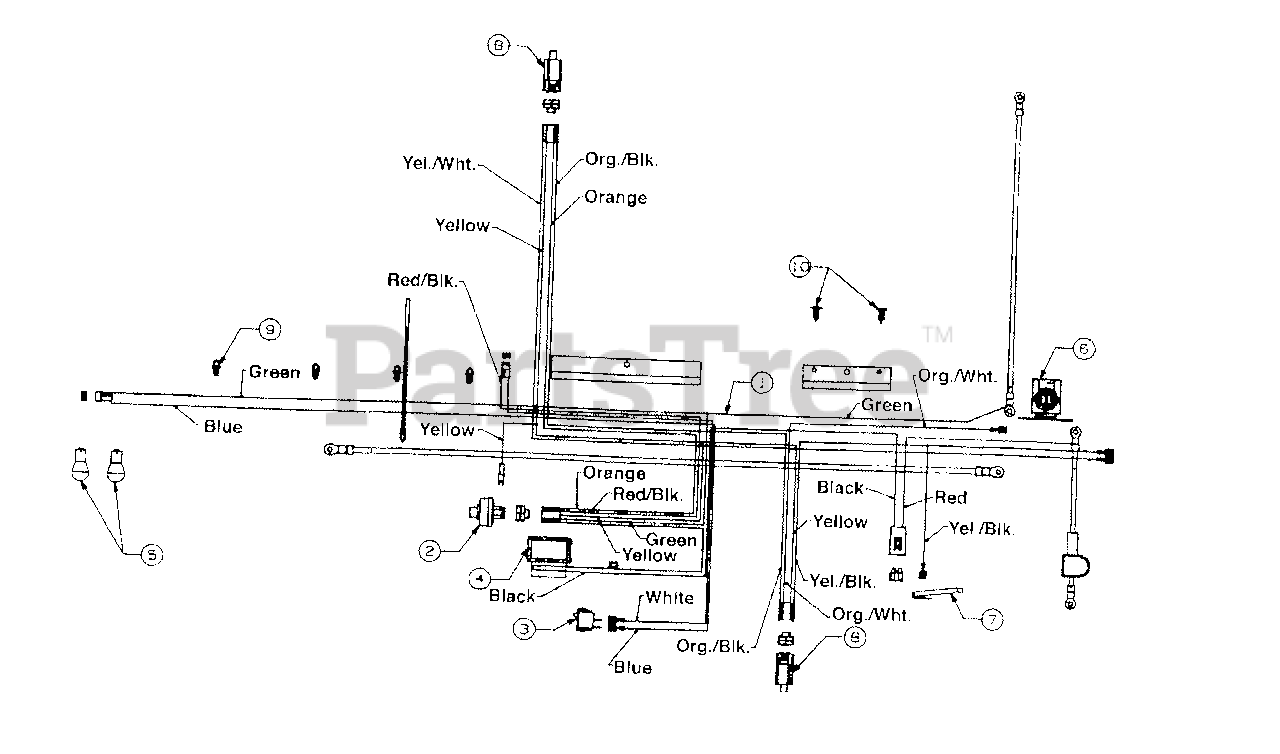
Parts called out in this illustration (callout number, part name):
1	Wire Harness w/Light Switch & Amp
2	Ignition Switch
3	Light Switch
4	Ammeter
5	Bulb (Headlight)
6	Solenoid
7	Safety Switch (Reverse)
8	Safety Switch
9	I Wire Retainer Clip
10	Ratchet
